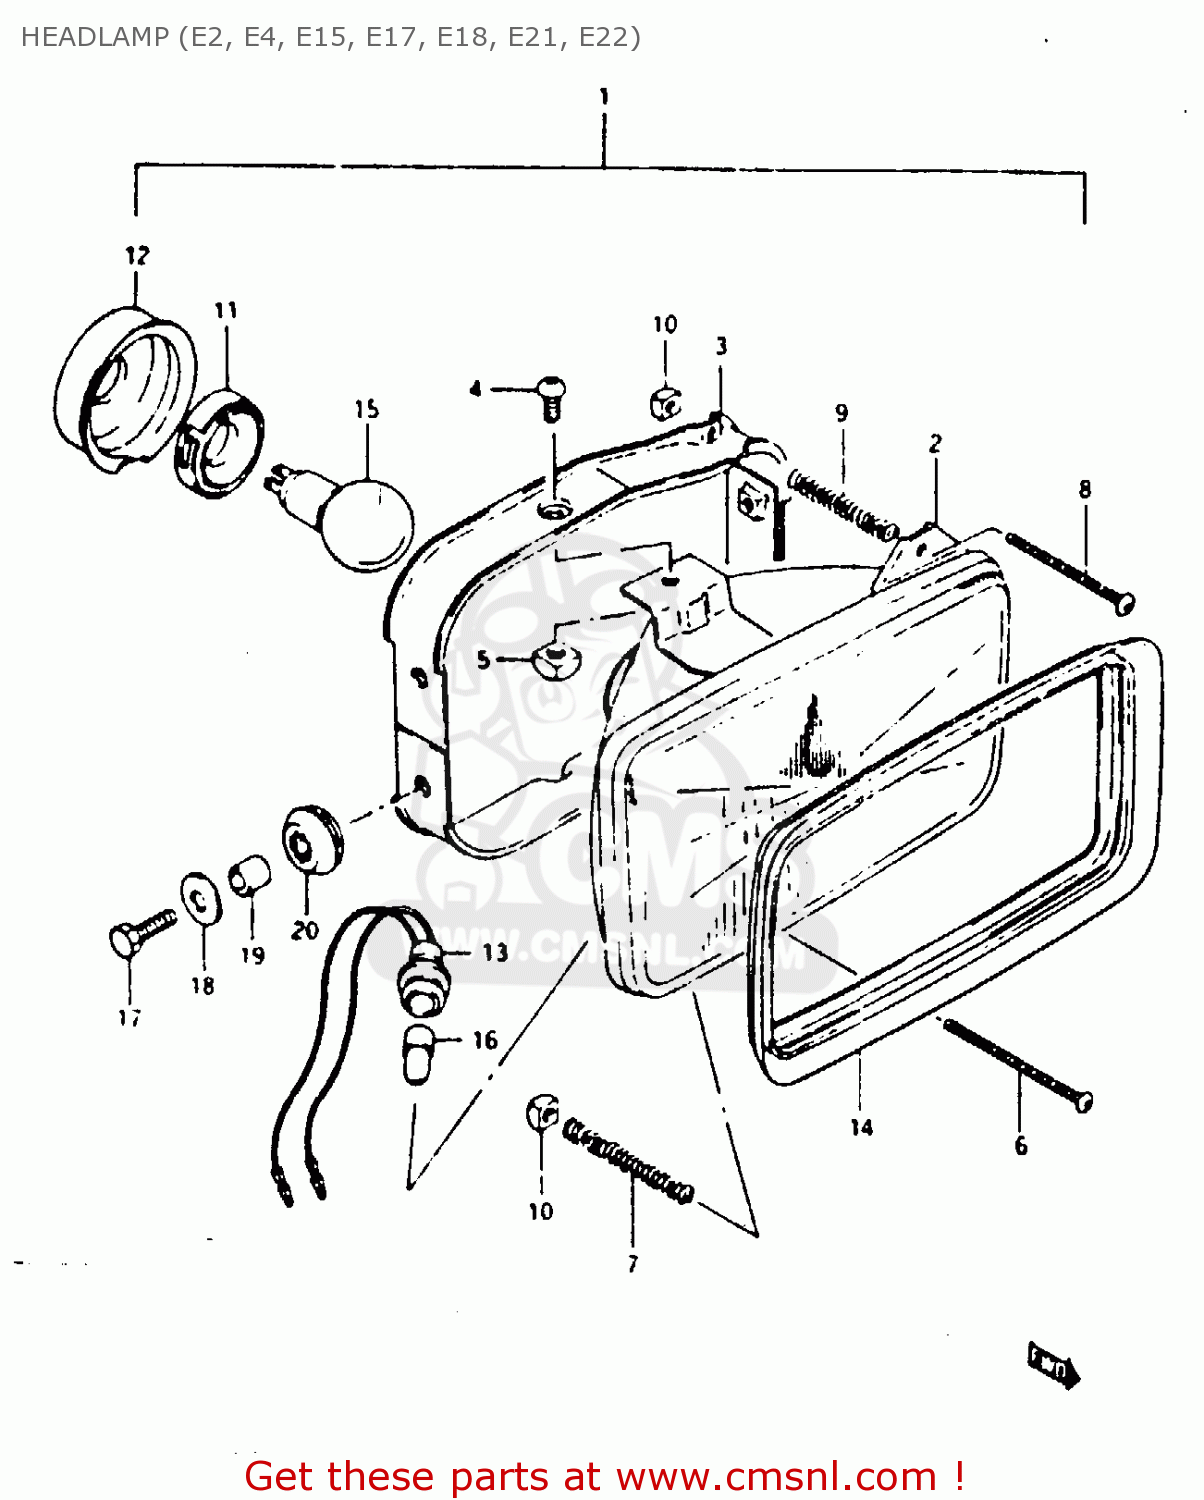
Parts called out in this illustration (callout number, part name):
1	HEADLAMP ASSY
2	UNIT
3	HOUSING
4	SCREW 5X12
5	NUT
6	SCREW,HEADLAMP ADJUST
7	SPRING
8	SCREW,HEADLAMP ADJUST
9	SPRING
10	NUT
11	HOLDER,BULB
12	COVER,SOCKET
13	SOCKET,PARKING
14	SHADE
15	BULB(12V45/40W)
16	BULB(12V4W)
17	BOLT
18	WASHER (6.5X20X1.2)
19	SPACER (6.8X10X10)
20	CUSHION
